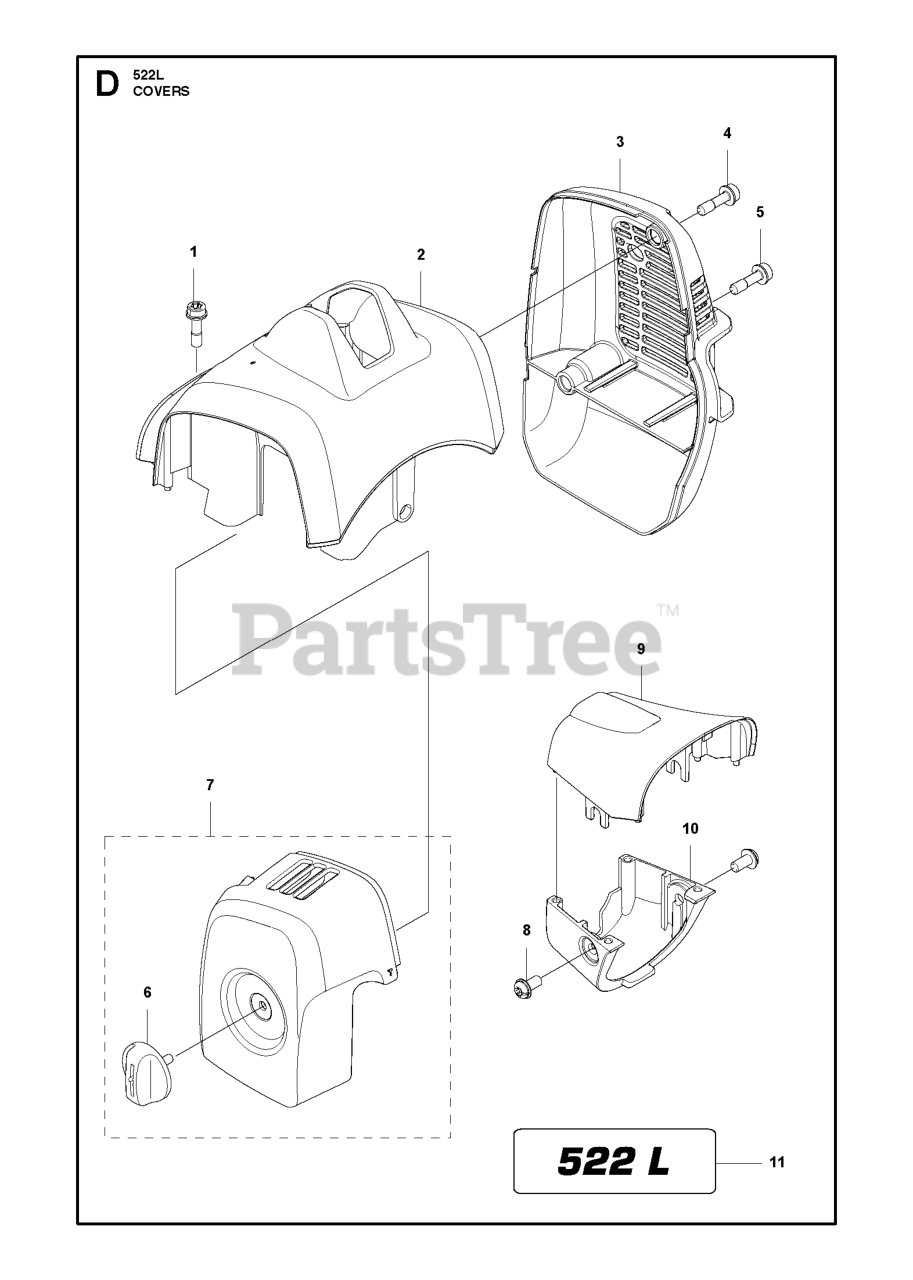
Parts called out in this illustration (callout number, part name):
1	BOLT
2	CYLINDER COVER
3	MUFFLER GUARD
4	BOLT
5	BOLT
6	KNOB CLEANER COLOR:GREY
7	FILTER COVER
9	COVER CLUTCH
10	COVER CLUTCH HOUSING LOWER
11	DECAL NAME 522L
